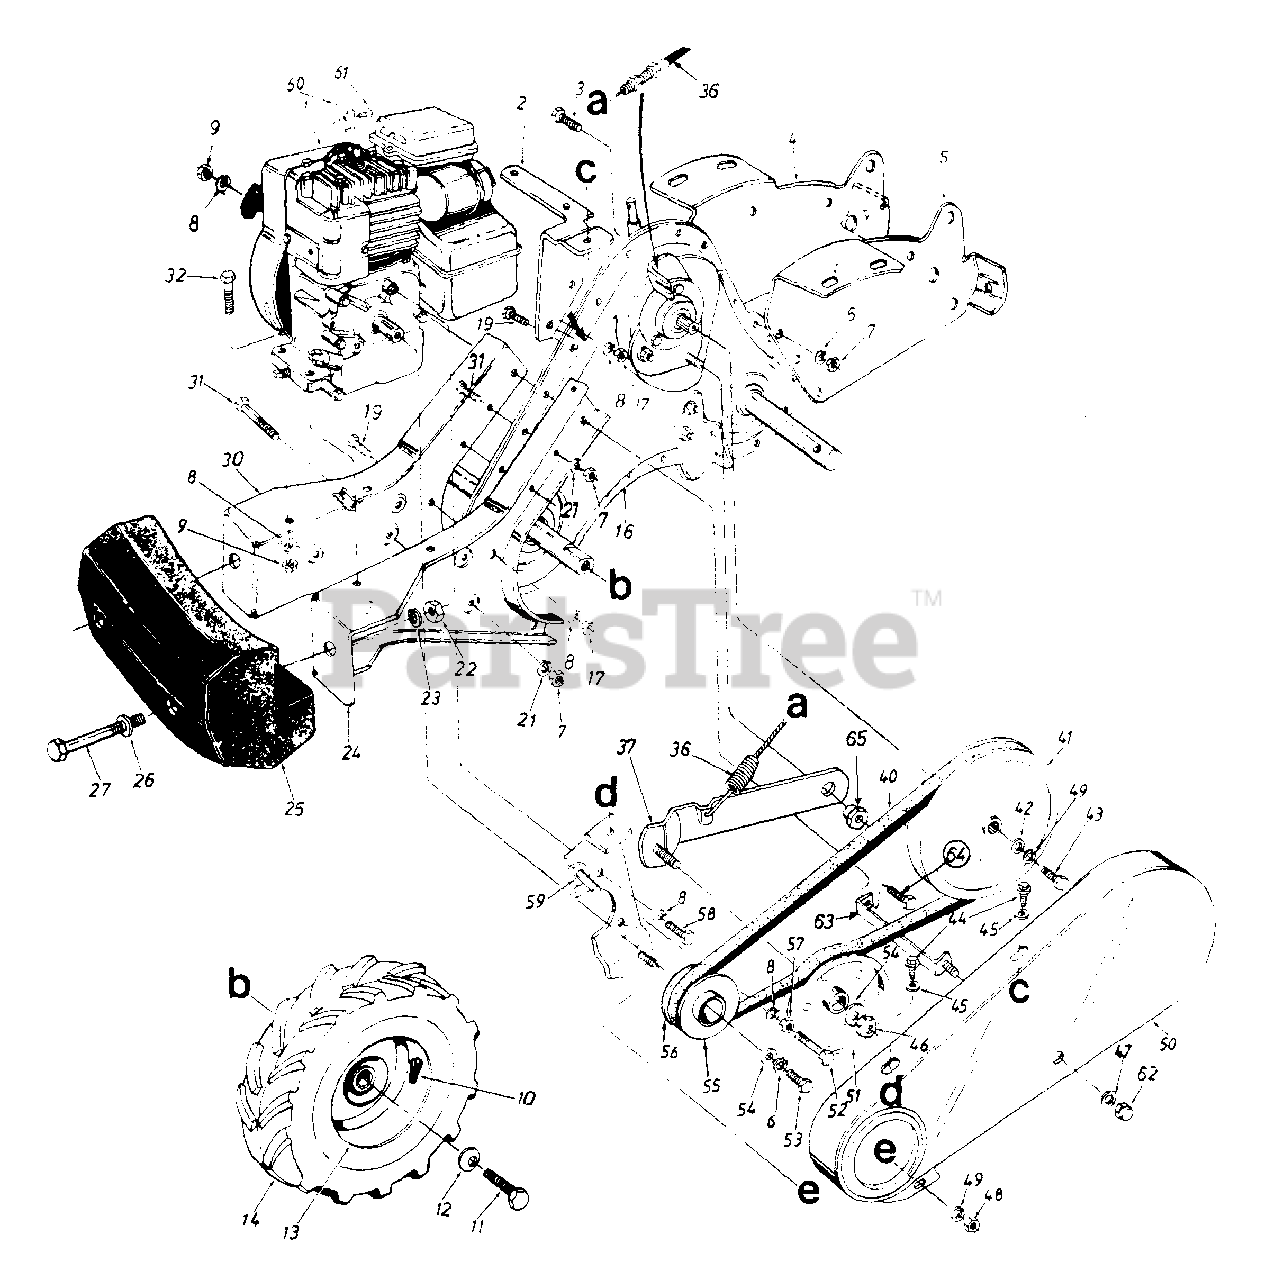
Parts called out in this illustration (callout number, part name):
1	Engine
7	Hex Nut 3/8-16 Thd
8	L-Wash. 5/16" I.D.
9	Hex Nut 5/16-18" Thd.
10	Air Valve
11	Hex Bolt 5/16-24 x .62" Lg.
12	Bell-Wash..345" I.D. x .88"
13	Wheel Rim Ass'y. Only
14	L.H. Wheel Ass'y. Comp.
17	Hex Nut 5/16-18 Thd.
19	Hex Bolt 5/16-18 x .75" Lg.
21	L-Wash. 3/8" I.D.- H.D.
22	Hex Nut 1/2-13 Thd.
23	L-Wash. 1/2" I.D.
26	Fl-Wash..510" I.D. x 1.0"
27	Hex Bolt 1/2-13 x 5.00" Lg.
32	Hex Bott 5/16-18 x 1.50"
36	Clutch Control Cable 46" Lg.
37	Idler Bracket Assembly
40	"V"-Belt
41	Fl-Pulley 8" O.D.
42	Fl-Wash. 1/4" I.D. x .93" O.D.
43	Hex Bolt 1/4-28 x .75" Lg.
44	Hex Wash. Hd S-Tap Scr 1/4-20 x .50" Lg
45	Fl-Wash .281" I.D. x .625"
46	Hex Cent L-Nut 3/8-24 Thd
47	Fl-Wash. 266" I.D. x.625" O.D.
48	Hex Nut 1/4-20 Thd
49	L-Wash. 1/4" I.D.
51	Fl-Idler w/Flanges 3.75" O.D.
52	Hex Bolt 5/16-24 x 1.75"
53	Hex Bolt 3/8-24 x 1 00" Lg.
54	Fl-Wash 3/8" I.D. x 1.00"
55	Outer Engine Pulley Half
56	Inner Engine Pulley Half
57	Hex Nut 5/16-24 Thd.
58	Hex Bolt 5/16-24 x .62" Lg
59	Belt Keeper Ass'y.
60	Casing Clamp
61	Hex Sems Scr. #10-32 x .62"
62	Hex Cap Nut 1/4-28 Thd.
63	Belt Cover Brkt. Ass'y.
64	Hex Bolt 5/16-18 x 1" Lg. (Gr. 5)
65	Shld. Nut
